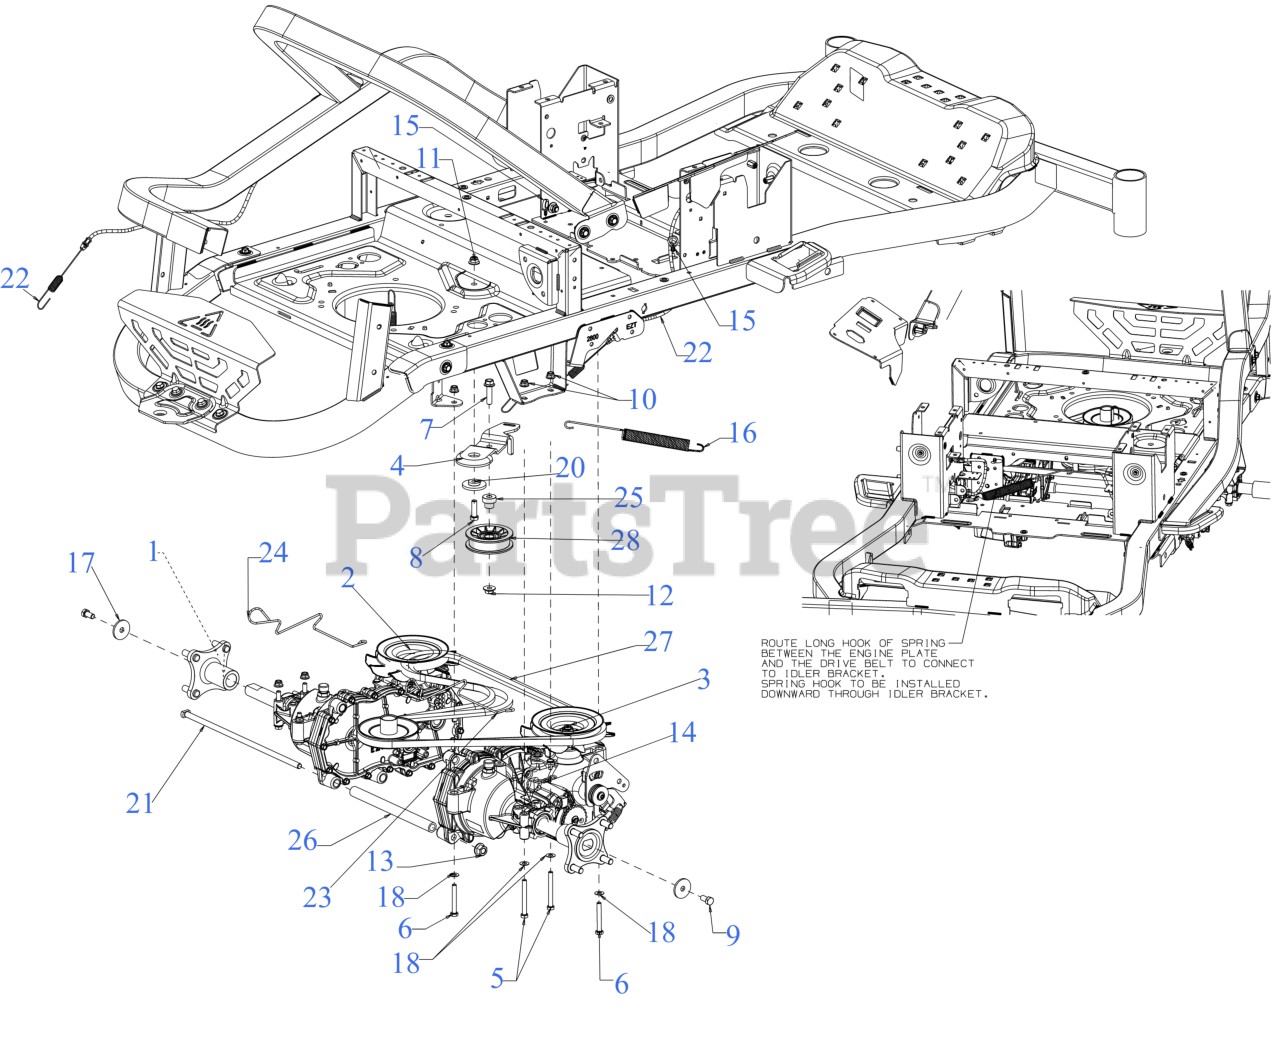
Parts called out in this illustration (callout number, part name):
1	WHEEL HUB ASSEMBLY
2	HYDRO TRANSMISSION (LH)
3	HYDRO TRANSMISSION (RH)
4	HYDRO DRIVE IDLER BRACKET
5	HEX SCREW 5/16-18 x 2.75
6	HEX SCREW 5/16-18 x 2.25 GR5
7	HEX HEAD BOLT (3/8-16:1.50 GR8)
8	SCREW 3/8-16 x 1.25 GR5
9	SCREW 3/8-16 x .75 GR 5
10	FLANGE LOCK NUT 5/16-18
12	FLANGE LOCK NUT
13	FLANGE LOCK NUT
14	BOW TIE COTTER PIN
15	CABLE RETAINER CLIP
16	EXTENSION SPRING .75 DIA X 10.27
17	FLAT WASHER .390x1.500x.134
18	FLAT WASHER
20	SHOULDER SPACER
21	SUPPORT TUBE ROD
22	PARK BRAKE CABLE
23	HYDRO BYPASS ROD (RH)
24	HYDRO BYPASS ROD (LH)
25	SHOULDER SPACER
26	SUPPORT TUBE
27	TRANSMISSION DRIVE BELT A x 67
28	FLAT IDLER PULLEY 3.00 OD
